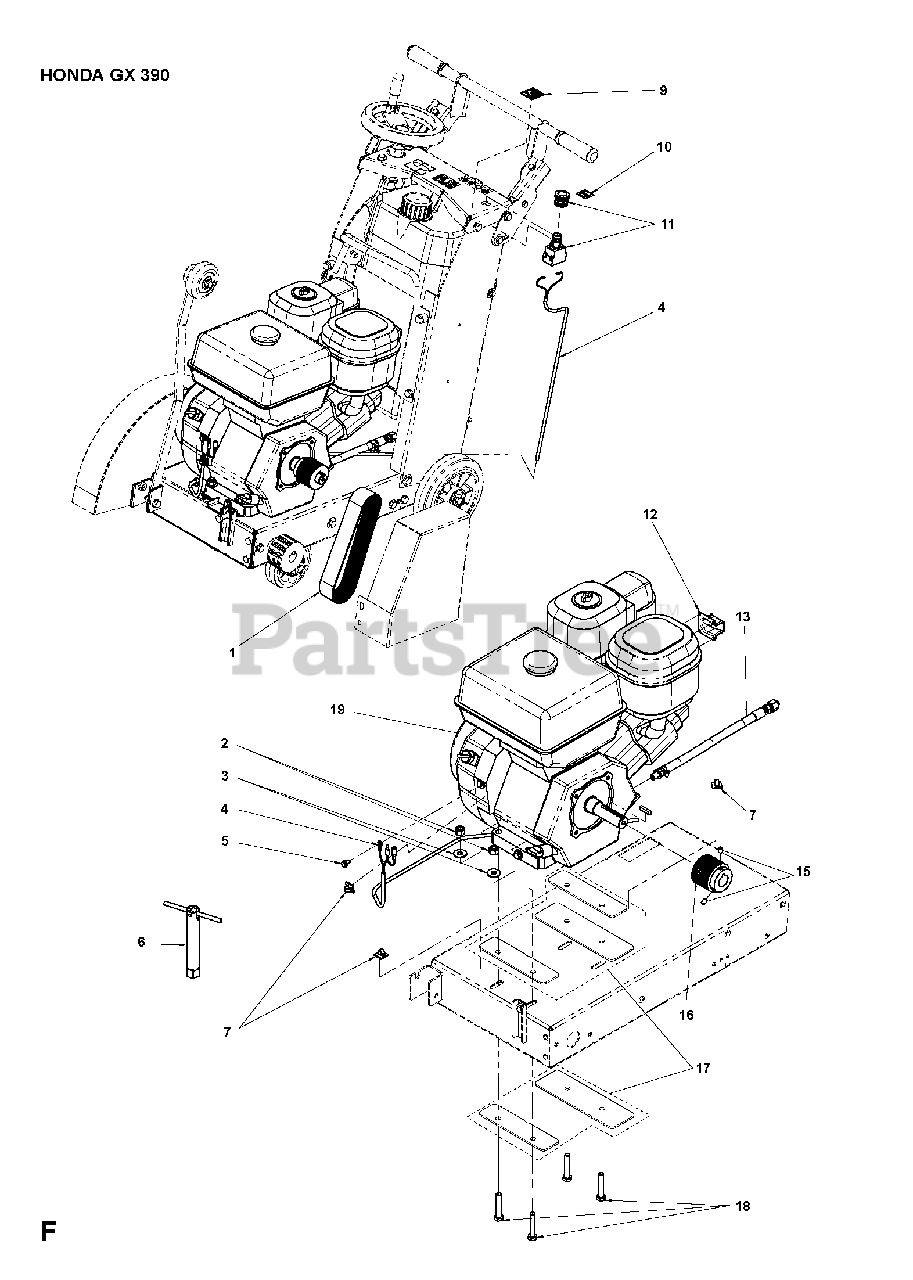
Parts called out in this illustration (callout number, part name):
2	HEXAGON LOCKING NUT
19	ENGINEHonda GX390UTQXC9
19	ENGINEHonda GX390H1-QXHQ
